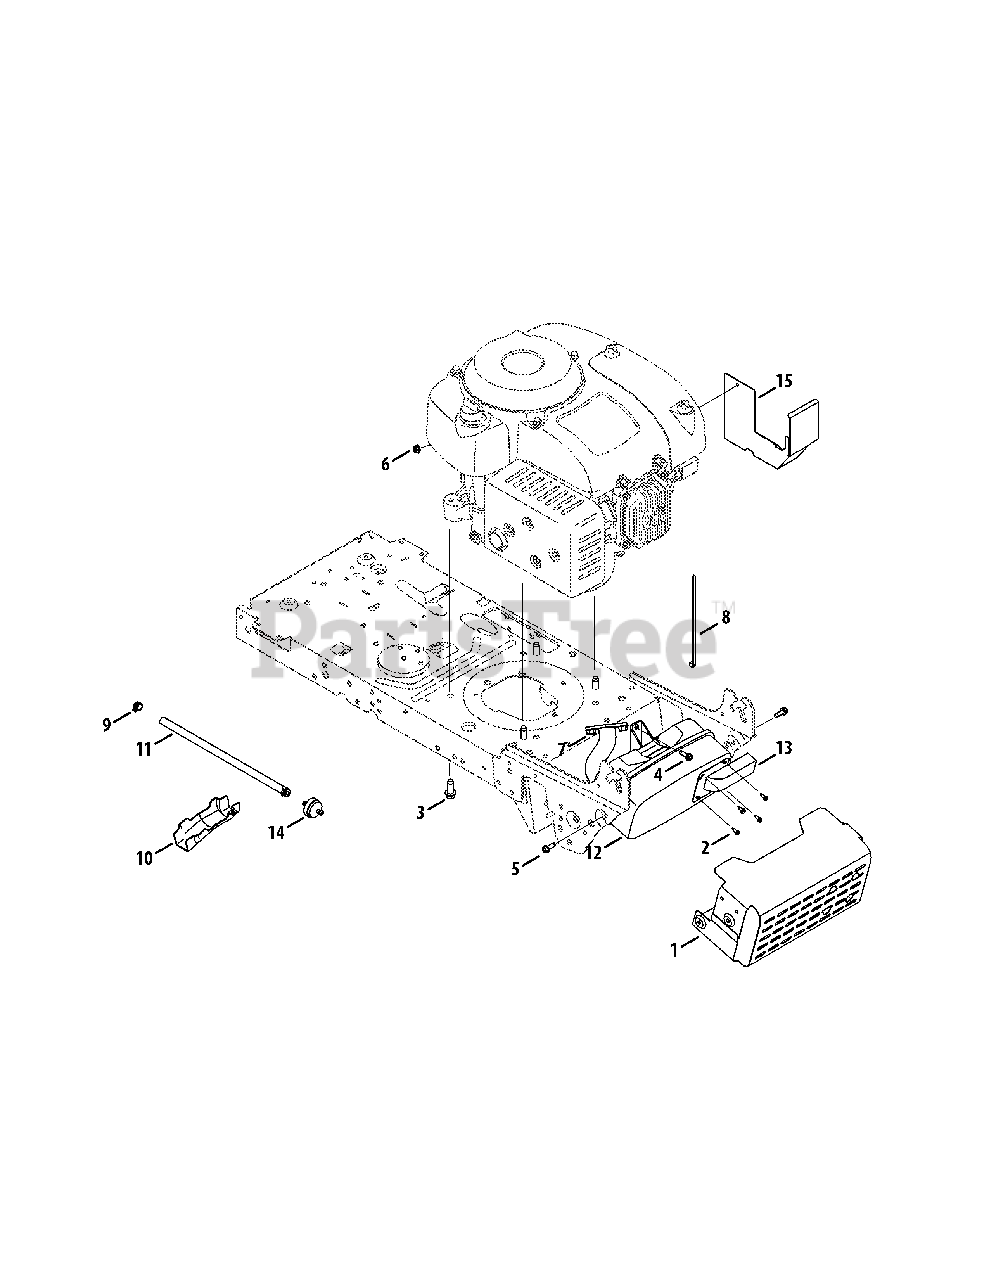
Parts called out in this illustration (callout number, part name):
1	Muffler Shield Assembly
2	Screw, 8-18 x .500
3	Screw, 3/8-16 x 1.0
4	Screw, 1/4-20 x .500
5	Screw, 1/4-20 x .750
6	Flangelock Nut, 1/4-20
7	Flange Nut, M8-1.25
8	Cable Tie
9	Clamp Hose, .490 diameter
10	Oil Drain Sleeve
11	Fuel Hose, Low Permeation
12	Muffler
13	Muffler Deflector
14	Fuel Filter
15	Deflector Bracket
